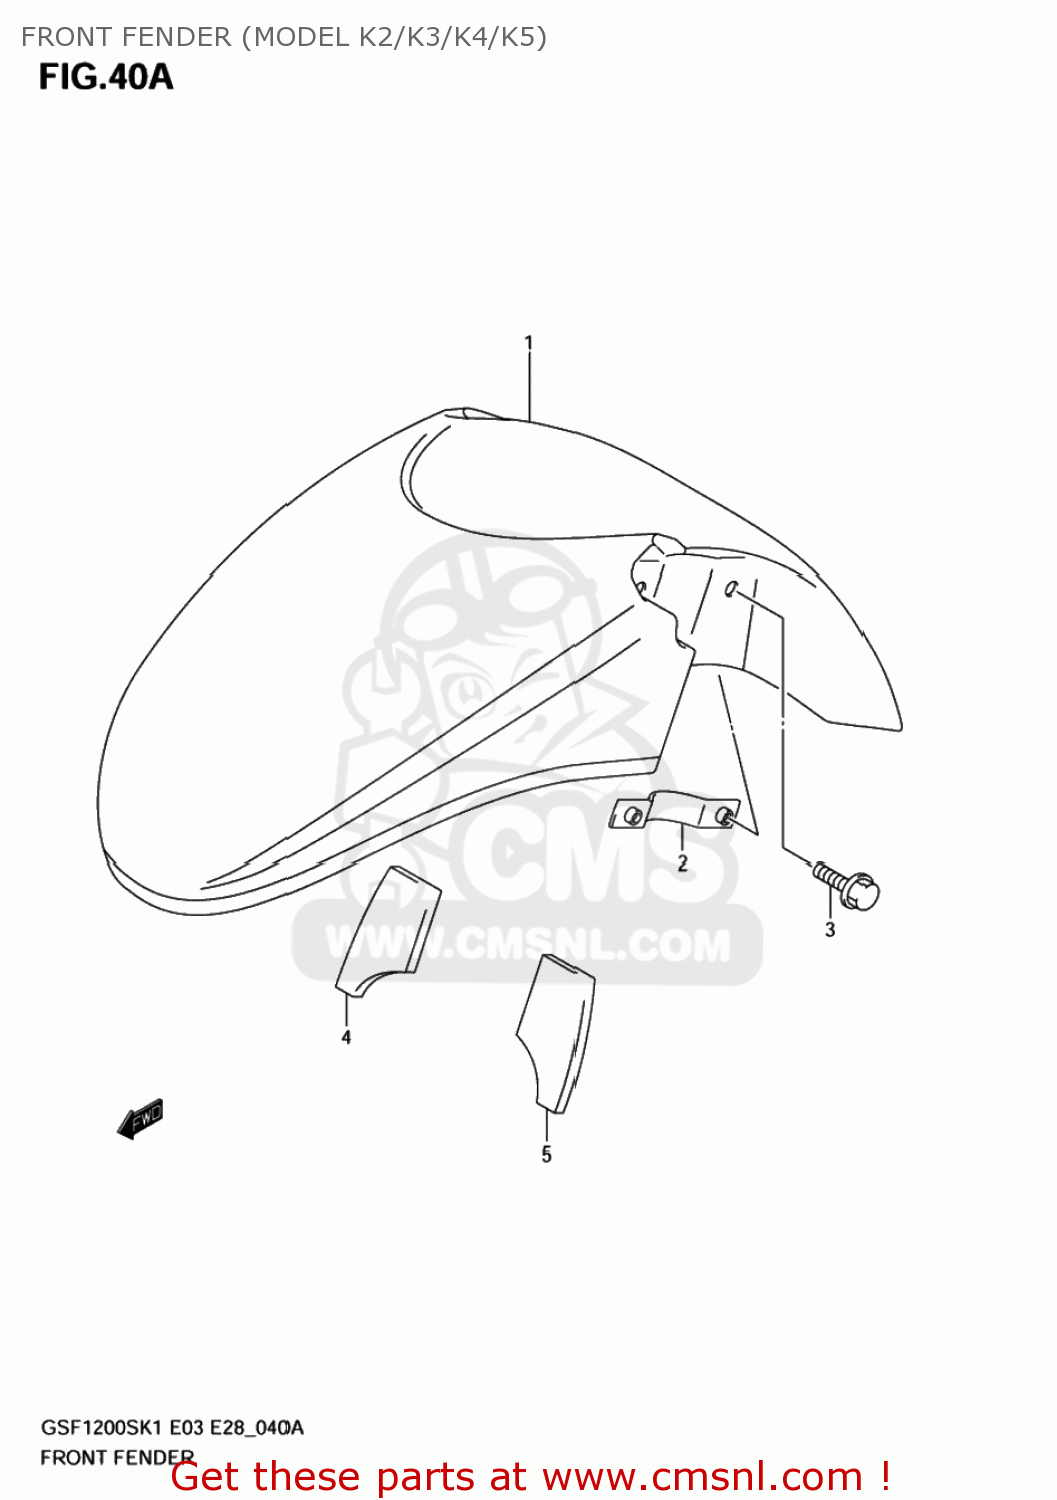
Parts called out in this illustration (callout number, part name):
1	FENDER,FR
2	PLATE,FR FENDER
3	BOLT
4	CUSHION,FR FENDER,R
5	CUSHION,FR FENDER,L
